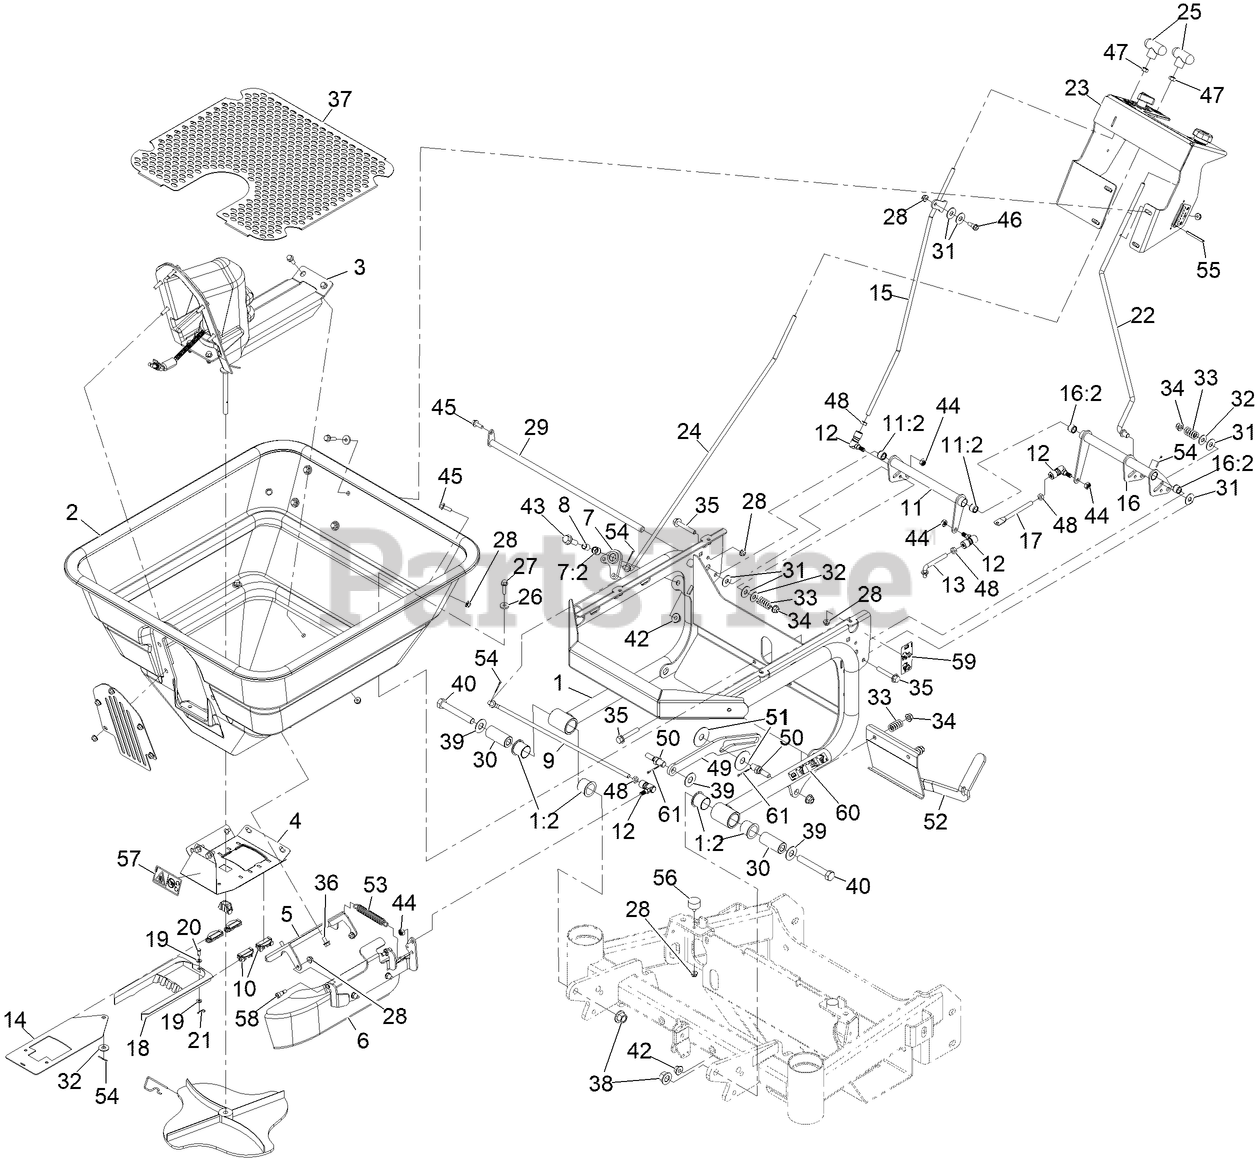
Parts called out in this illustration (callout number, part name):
1	FRAME-HOPPER
1:2	BUSHING-PIVOT
2	HOPPER -150 LB
3	ASM-Motor, Hopper
4	PLATE-HOPPER, BOTTOM
5	BRACKET-HOPPER DEFLECTOR
6	ASM-Deflector, Side
7	CRANK-DEFELCTOR
7:2	BUSHING
8	BUSHING-PIVOT, DEFLECTOR
9	LINKAGE-DEFLECTOR, LOWER
10	GUIDE-RATE, GATE
11	CRANK-GATE, HOPPER
11:2	BUSHING
12	Ball Joint-Quick Disconnect, SS
13	LINKAGE-GATE, LOWER
14	RATE-GATE
15	LINKAGE-GATE, UPPER
16	CRANK-DIFFUSER
16:2	BUSHING
17	LINKAGE-DIFFUSER, LOWER
18	DIFFUSER
19	WASHER-FLAT
20	PIN-CLEVIS
21	PIN-COTTER, HAIR
22	LINKAGE-DIFFUSER, UPPER
23	ASM-Console, Hopper
24	LINKAGE-DEFLECTOR, UPPER
27	SCREW-HHF
28	Nut-Hex Flange
29	SHAFT-CONTROL, HOPPER
30	SPACER-PIVOT, HOPPER
32	FLAT WASHER, 5/16 NOM,ST
33	SPRING-COMPRESSION
34	Nut-Hex Flange
35	SCREW-HHF
36	SCREW-HWH
37	SCREEN-HOPPER, MEDIUM
38	NUT-HEX FLANGE
40	SCREW-HH
42	Nut-Hex Flange
43	SCREW-HHF
44	NUT-LOCK, NI
45	Screw-HHF
46	BOLT-SHOULDER
47	NUT-HEX
48	Nut-Hex
49	STRAP-HOPPER
50	PIN-PIVOT
51	WASHER-FLAT, 1/2, SS
52	LATCH-HOPPER
53	SPRING-EXTENSION
54	COTTER PIN 5/64X3/4 18-8
55	PIN-ROLL, 3/16 X 2.0
56	BUMPER-RUBBER
57	Decal-Dismemberment Hazard
58	BOLT-SHOULDER
59	DECAL-HOPPER ROTATE
60	DECAL-HOPPER LATCH
61	Pin-Cotter
